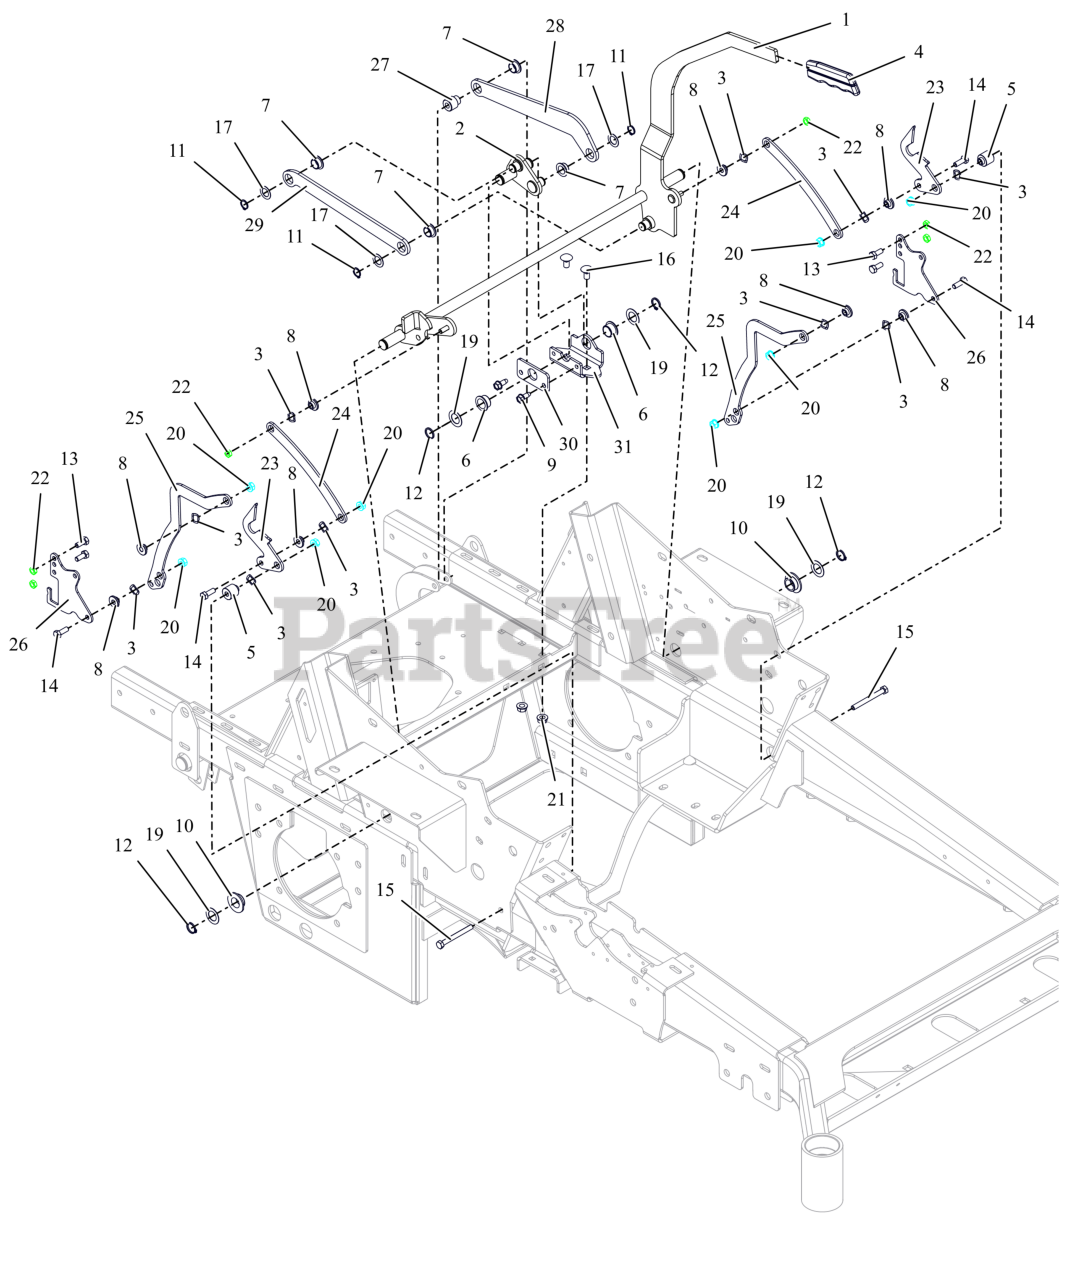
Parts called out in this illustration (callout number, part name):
1	WLDMT, PARKING BRAKE ARM
2	WLDMT, BRAKE ACTIVATION PIVOT
3	WAVE WASHER .531X.781X.125FH
4	GRIP, PARKING (GRAY)
5	BUSHING FLANGED - .318X.500X.972X.875
6	BSHG, FLANGE .750 X .875 X .5000 X 1.125
7	BSHG, FLANGE .625 X .750 X .375 X 1.000
8	BSHG-FLG .32X.500X.344X.880
9	SCR,TAP .312-18X.75 HWH TR ZCC
10	BSHG, FLANGED .762 X 1.48 X .44 IGLIDER
11	RG-RTNG-EXT .625X.050
12	RG-RTNG-EXT .689X.078
13	BLT,HEX .31-18X.75 G5 ZCC
14	BLT, HEX .31-18X.875 G5 ZCC
15	BLT, HEX .31-18X3.00 G5 ZCC
16	BLT, RHSN .38-16X.750 G5 ZCC
17	WSHR-THRST .625 X 1.0 X .03
19	WSHR-HDND-THRST .758X1.23X.031
20	NUT,LK-CTR-FLG .31-18 GF ZCC
21	NUT-LK-CTR-FLG .375-16 GF ZCC
22	NUT-LK-CTR-JAM .312-18 GB ZCC
23	BRKT, BRAKE - RTN (BLACK)
24	BRKT, LINK - BREAK RTN (BLACK)
25	LINK- SPEED CONTROL -HTJ (BLK)
26	BRKT, SPEED - HTG (BLACK)
28	LINK, BRAKE ACTIVATION REAR
29	LINK, BRAKE ACTIVATING FRONT
30	PLATE, BSHG MOUNTING
31	BRKT, BSHG MTG
